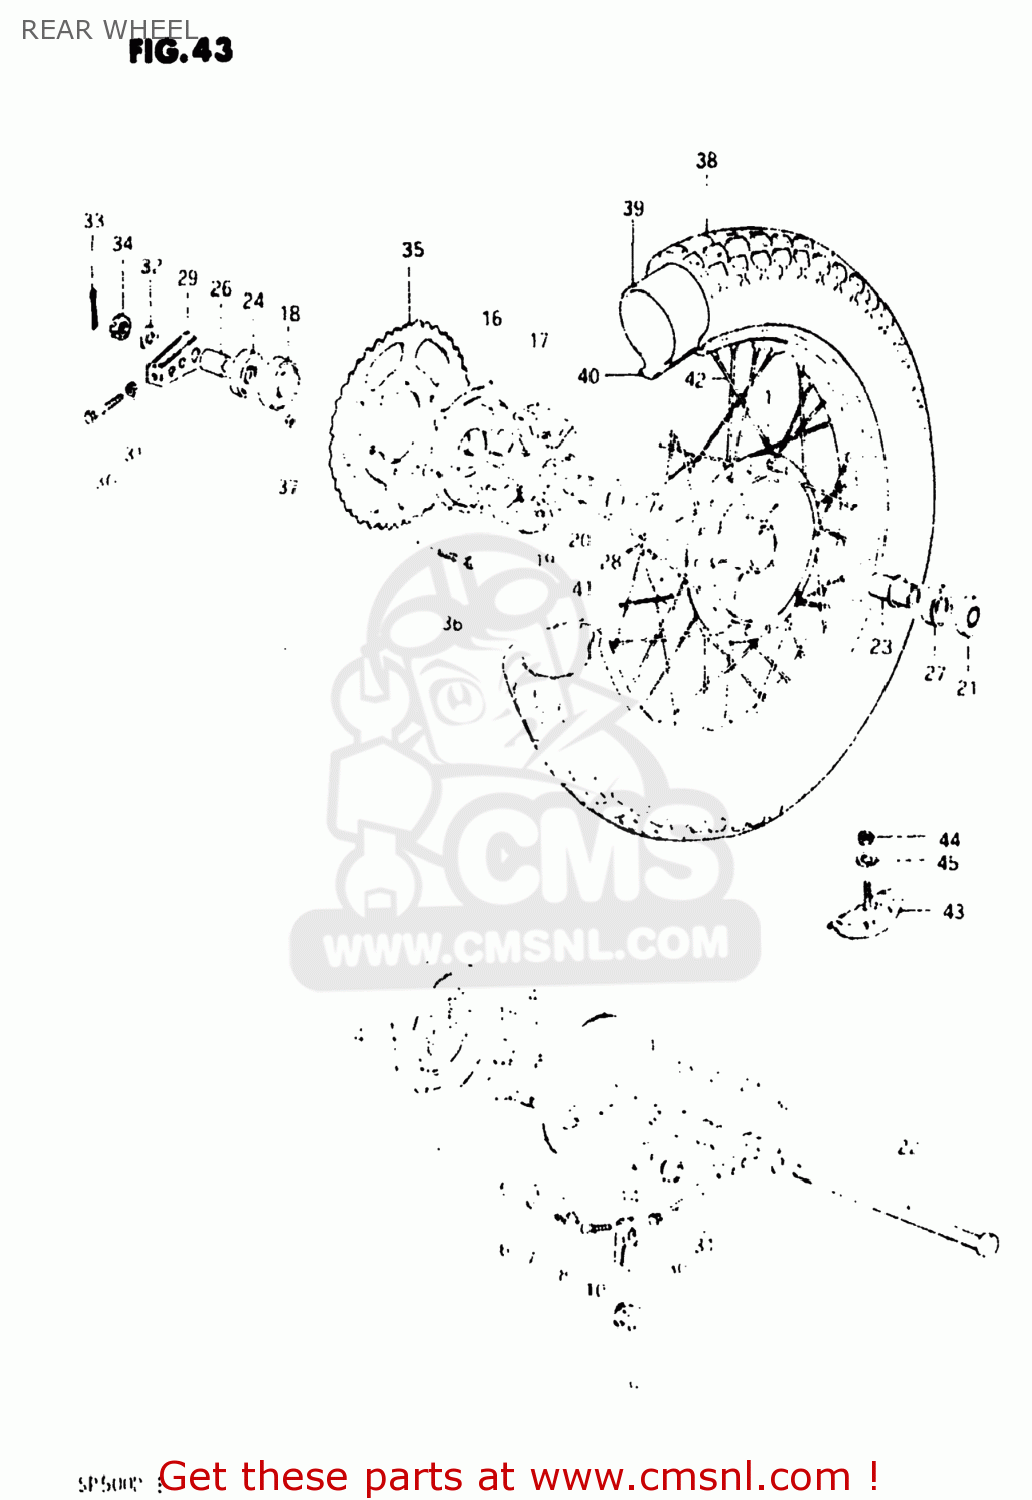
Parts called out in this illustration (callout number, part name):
1	DRUM,REAR HUB
2	PANEL,REAR HUB
3	SHOE,BRAKE (MCA)
4	SPRING
5	CAM,FRONT BRAKE
6	O-RING,BOSS
7	WASHER (15X24X1.6)
8	SPRING
9	LEVER,REAR BRAKE CAM
10	BOLT
11	BEARING(24X31X28)
12	WASHER
13	CVR,RR BRAKE AHR PNL DUST SEAL
14	SPHERICAL BRNG,TORQUE LINK
15	SPACER,REAR HUB PANEL
16	DRUM,REAR SPROCKET MOUNT
17	ABSORBER,RR HUB SHOCK
18	BEARING
19	O-RING
20	SPACER,REAR SPROCKET DRUM
21	OIL SEAL
22	AXLE,REAR
23	SPACER,REAR HUB BEARING
24	SEAL,OIL(30.5X52X8)
25	SPACER,REAR AXLE,RIGHT
26	SPACER(17X30.5X16.3)
27	BEARING
28	BEARING
29	ADJUSTER,CHAIN
30	BOLT
31	NUT
32	WASHER (17X30X3.2)
33	PIN,COTTER
34	NUT
35	SPROCKET,REAR (NT:46)
36	BOLT
37	NUT
38	TIRE
39	TUBE,INNER
40	PROTECTOR,WHEEL,INNER
41	RIM,REAR WHEEL
42	SPOKE ASSY,RR WHEEL
43	STOPPER,BEAD
44	NUT
45	WASHER
